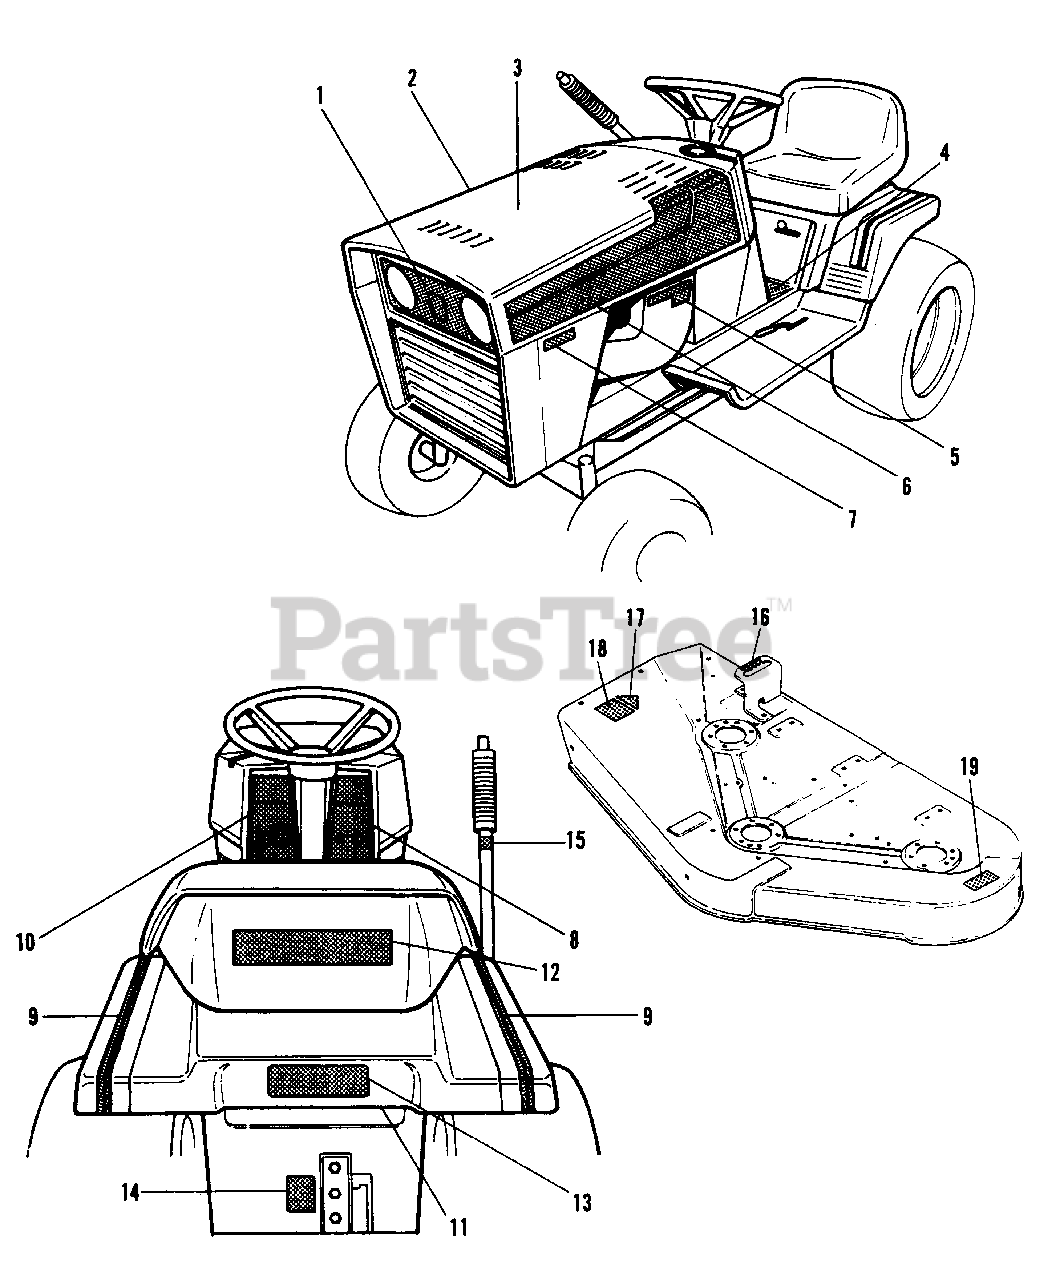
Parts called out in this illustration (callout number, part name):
1	DECAL, Grille
2	DECAL, Hood Stripe, R.H.
3	DECAL, Drive Belts
4	DECAL, Shift Pattern
5	DECAL, Engine, 16 H.P.
5	DECAL, Engine, 12.5 H.P.
6	DECAL, Hood Stripe, L.H.
7	DECAL, 6211
8	DECAL, Dash, R.H. (6211 Only)
8	DECAL, Dash, R.H. (6212.5 & 6216 Only)
9	DECAL, Seat Deck
10	DECAL, Dash, L.H. (6211 Only)
10	DECAL, Dash, L.H. (6212.5 & 6216 Only)
11	DECAL, Battery
12	DECAL, Seat (Simplicity)
13	DECAL, Cast Iron Trans.
14	DECAL, Rear P.T.O.
15	DECAL, Lift Lever
16	DECAL, Mower Height
17	DECAL, OPEI
18	DECAL, Warning
19	DECAL, Danger
